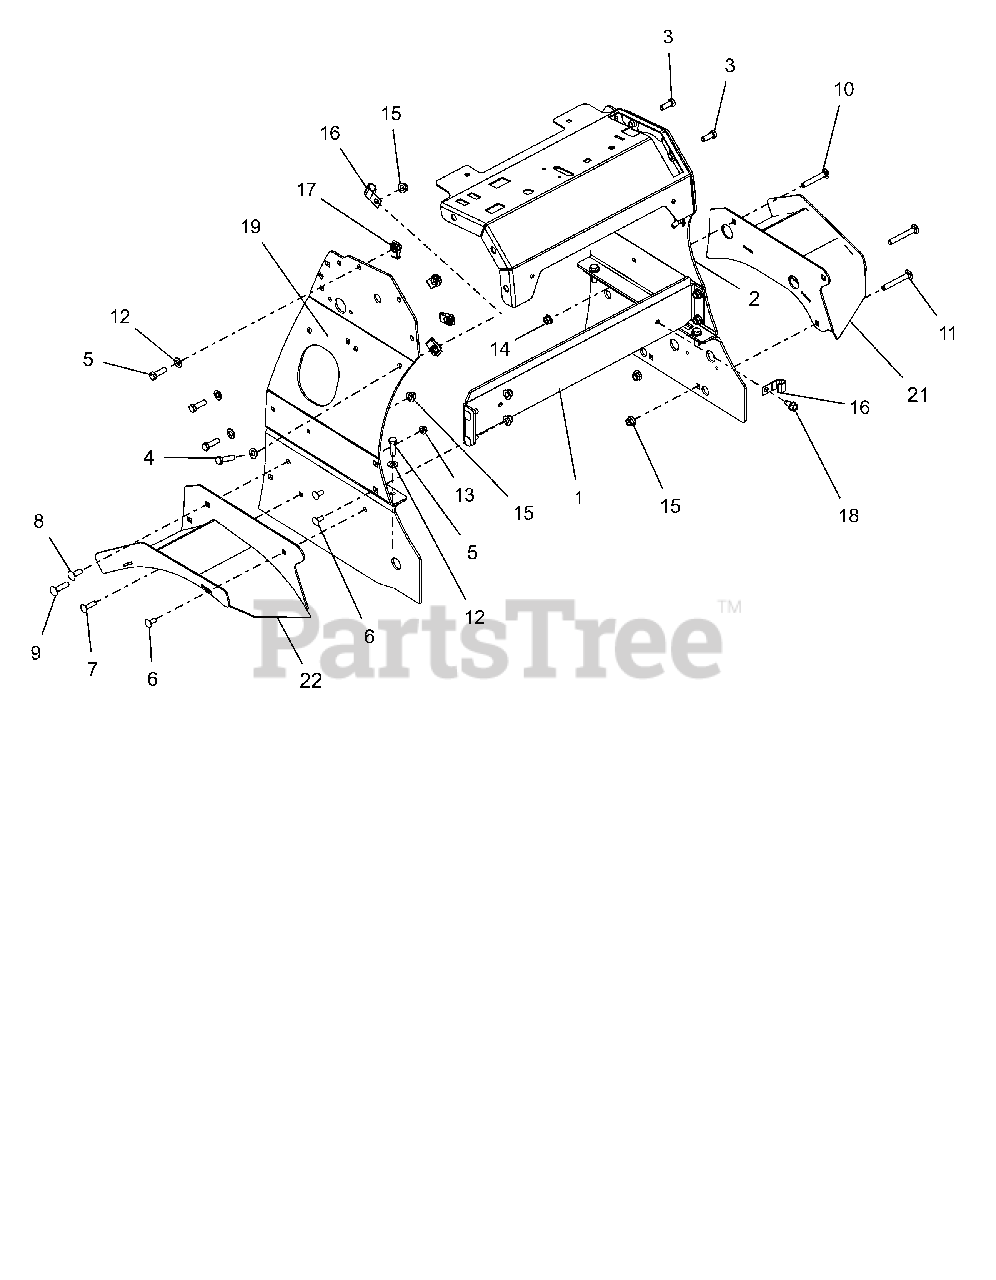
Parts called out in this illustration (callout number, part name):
1	STIFFENER, TOWER
2	PANEL, LH TOWER SIDE
3	@BLT-HEX .38-16X1.00 GR5 YWZC
4	@BLT-HEX .38-16X1.50 GR5 YWZC
5	@BLT-HEX .38-16X1.25 GR5 YWZC
6	@BLT-RDHDSQNK .31-18X.75 G5YZ
7	@BLT-RDHDSQNK .31-18X1.25 G5YZ
8	@BLT-RDHDSQNK .38-16X1.00 G5YZ
9	@BLT-RDHDSQNK .38-16X1.50 G5YZ
10	@BLT-RDHDSQNK .38-16X2.50 G5YZ
11	@BLT-RDHDSQNK .38-16X2.75 G5YZ
12	@WSHR-FL-STL.406X.812X.065 YWZ
13	@NUT-SPNLK-FLG .312-18 YWZC
14	@NUT-LK-TOP-FLG .38-16 YWZC
15	@NUT-LK-NYL-FLG .38-16 YWZC
17	NUT-RTNR .375-16X.37
18	@SCR-TAP .38-16X.75 HWH TR YWZ
19	KIT, SERVICE RH TOWER
21	WLDMT, LH FENDER
22	WLDMT, RH FENDER
